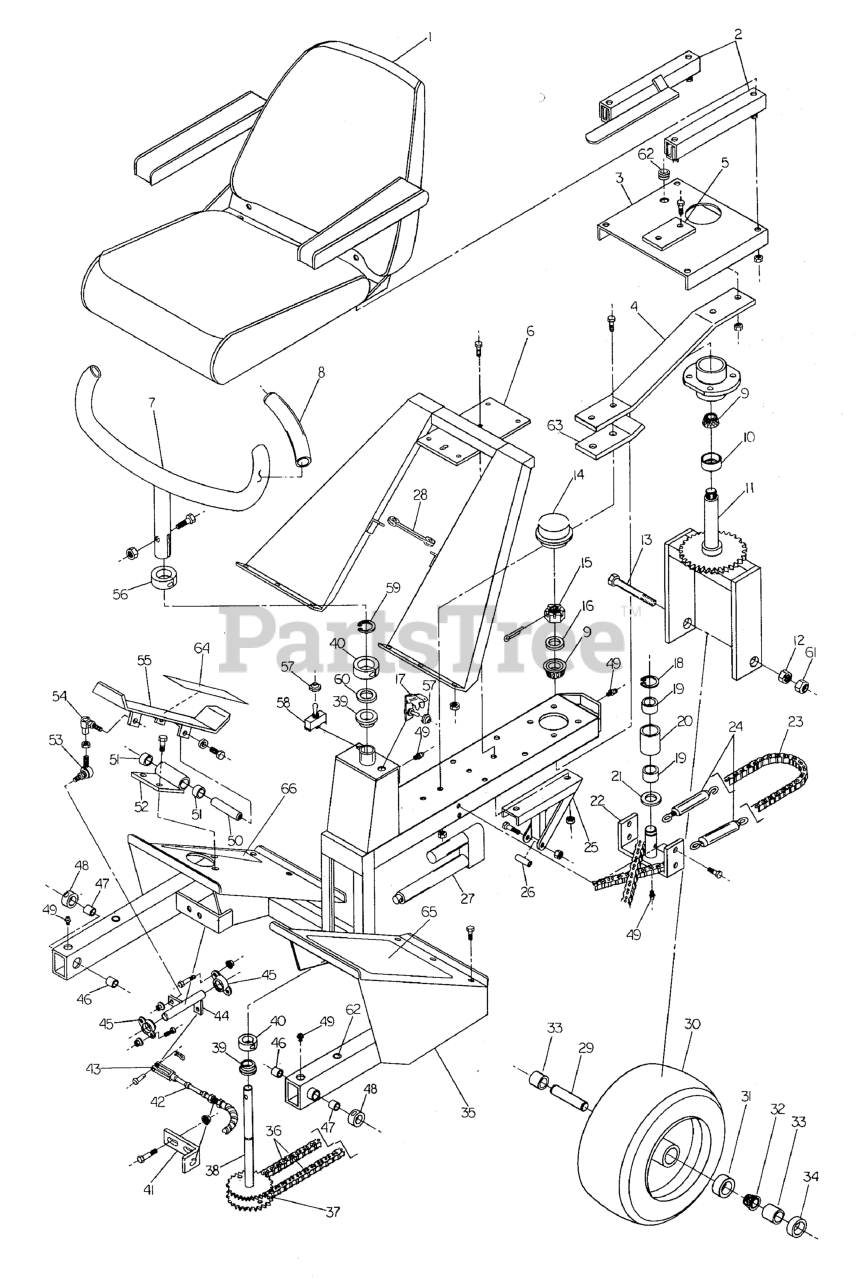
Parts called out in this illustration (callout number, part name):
1	SEAT, Black & Silver, Complete
1	CUSHION, BACK
1	CUSHION, BOTTOM
1	ARM REST, RH
1	ARM REST, LH
2	SEAT ADJUSTER RAILS (set of 2)
3	PLATE, Seat
4	SEAT SPRING
5	SUPPORT, Seat Plate
6	Rider Frame Support
7	STEERING HANDLE
8	GRIP, Foam
9	BEARING, Tapered Roller
10	SEAL, GREASE
11	MOUNT, Steering Tire
12	NUT, 5/8-11 Hex
13	BOLT, 5/8-11 x 9-1/2
14	CAP
15	NUT, 3/4-16 Hex Slotted
16	WASHER, 3/4 SAE
17	Toggle Switch
17	Switch Guard
18	SNAP RING, External
19	BUSHING, Brass
20	CHAIN ROLLER
22	Chain Roller Mount
23	CHAIN, #40 Roller, 36 Links
24	TURNBUCKLE
25	Actuator Mount
26	Actuator Spacer
27	Electric Actuator
28	RUBBER STRAP
29	STEERING TIRE AXLE
30	WHEEL & TIRE ASSEMBLY, 18 x 7.5 x 8, White, Complete
31	BEARING CUP
32	BEARING, Tapered Roller
33	SPACER, 1.01 X 1.25 X 2.06
34	GREASE SEAL
35	Rider Frame
36	CHAIN, #40 Roller, 31 Links
37	CONNECTOR, #40 Chain Link
38	SHAFT, Steering Sprocket
39	BUSHING, Flange
40	COLLAR, 1-1/4" Split
41	CABLE BRACKET
42	CABLE, Speed Control
44	BELL CRANK
45	BEARING, Flange
46	BUSHING
47	BUSHING, Brass
48	COLLAR, 3/4" Split
49	GREASE FITTING
50	SHAFT, Pedal Pivot
51	BUSHING, Brass
52	FOOT PEDAL PIVOT MOUNT, Complete
53	BALL JOINT, 3/8-24 Male, Studded
54	BALL JOINT, 3/8" Female Studded
55	FOOT CONTROL PEDAL
56	COLLAR, 1" Split
57	Toggle Boot
58	Toggle Switch
59	Snap Ring
60	SHIM
61	NUT, 5/8-11 Hex Side Lock
62	GROMMET, 1/2"
63	SUPPORT, Seat Spring
64	SAFETY WALK
65	SAFETY WALK
66	SAFETY WALK
